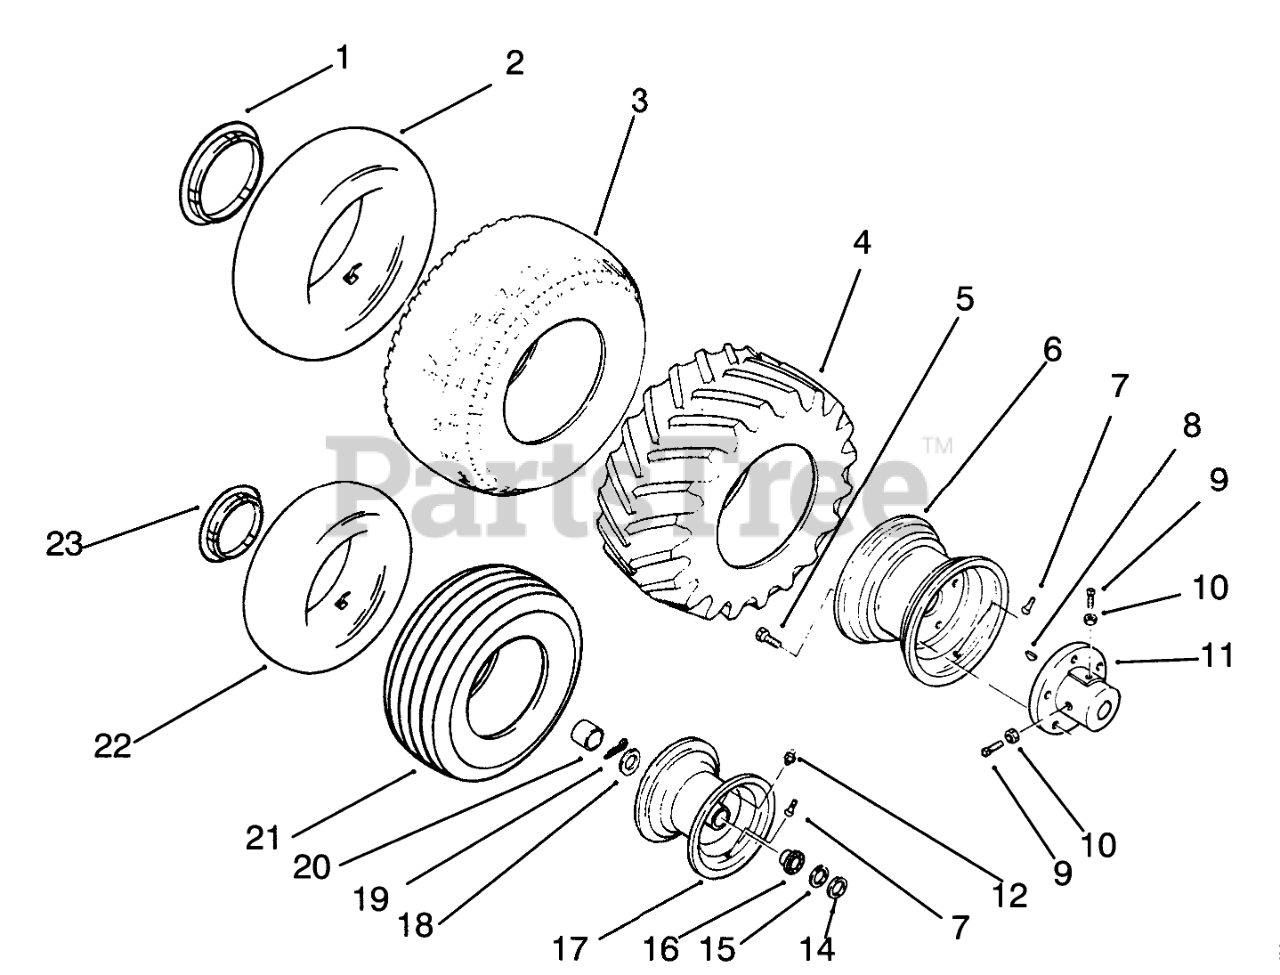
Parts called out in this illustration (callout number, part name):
1	12"-HUB CAP LOGO
2	Tube-Rear (Opt.)
3	TIRE-23X8.50-12 2PLY
4	Tire-Cleat, Rear
5	BOLT-LUG
6	WHEEL
7	VALVE
8	Key-Woodruff
9	SCREW-SET, SQH
10	NUT-JAM
11	Hub-Rear
12	ZERK-GREASE
14	WASHER-SHIM
15	WASHER
16	BEARING-WHEEL
17	Wheel Assembly-Front (Incl. Ref. #7, 12, & 16)
18	WASHER-WHEEL
19	PIN-COTTER
20	HUB CAP-FLAT BLACK
21	TIRE-15 X 6.00-6
23	6"-HUB CAP LOGO
